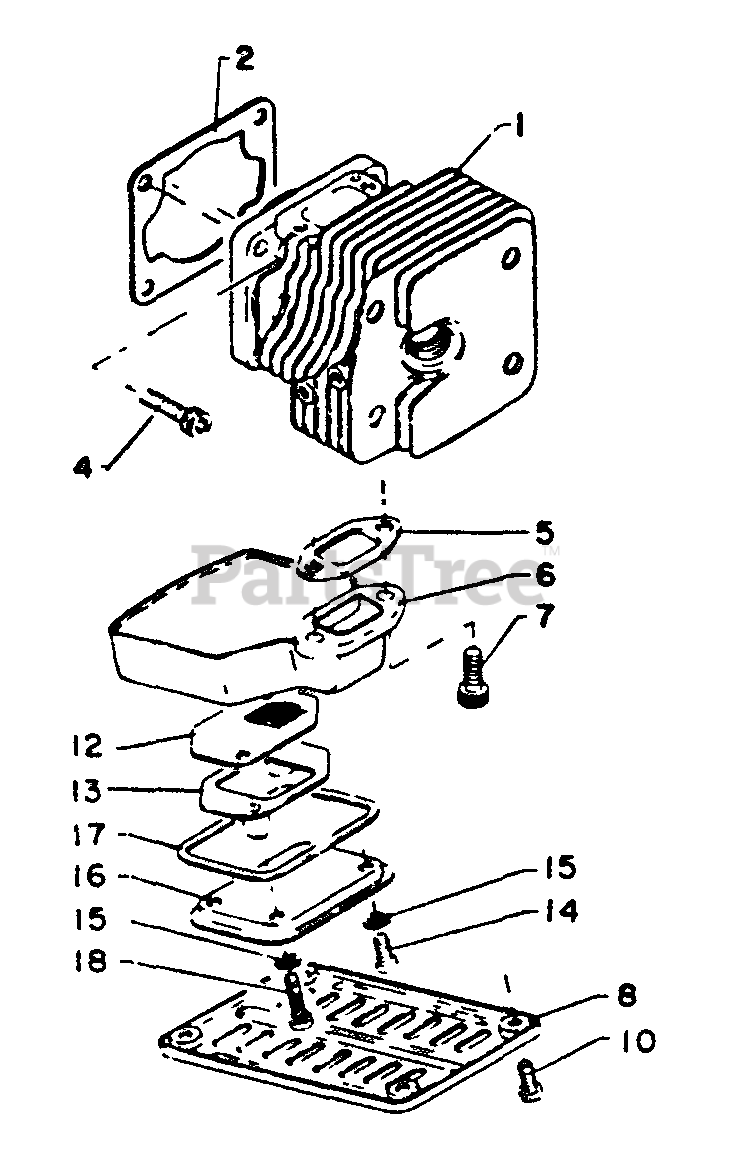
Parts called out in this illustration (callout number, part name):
1	CYLINDER
2	GASKET, CYLINDER
4	SCREW - 5×20
5	GASKET, EXHAUST
6	COVER, MUFFLER
7	SCREW - 5×15
8	COVER, MUFFLER
10	SCREW - 4×10
12	SCREEN, SPARK ARRESTER
13	RETAINER, SCREEN
14	SCREW 4×6
15	WASHER, LOCK 4 MM
16	COVER, MUFFLER
17	GASKET, EXHAUST
18	SCREW 4×14
